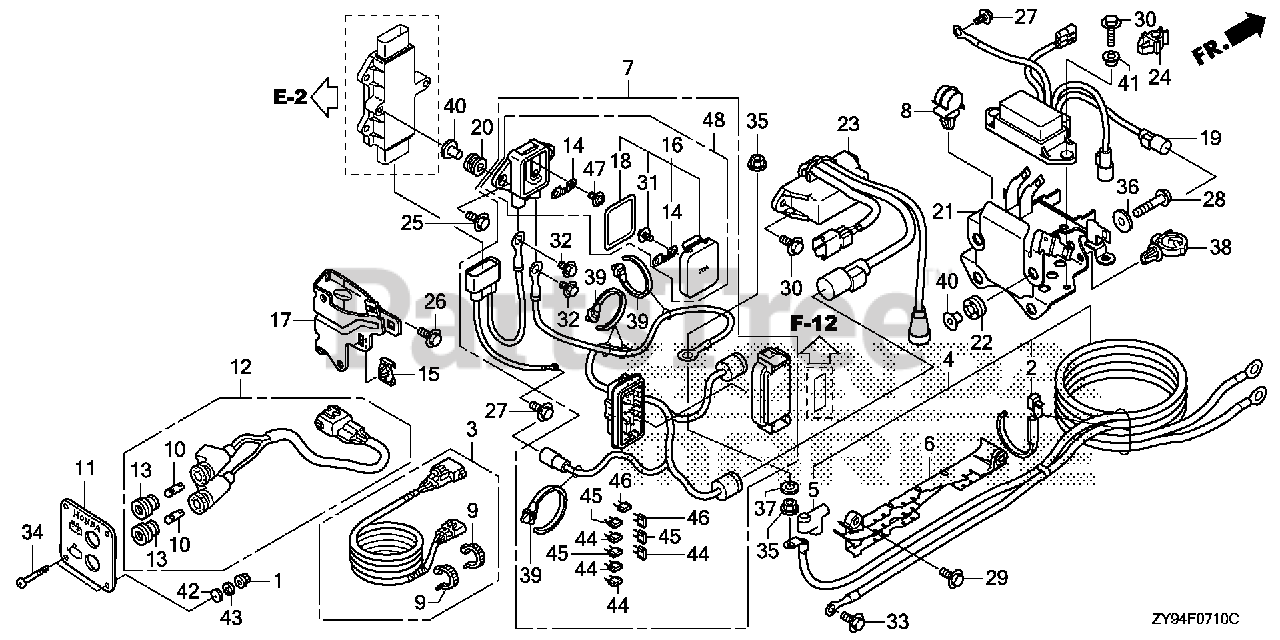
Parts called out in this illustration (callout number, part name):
1	NUT, FLANGE (5MM)
2	BAND, WIRE
3	WIRE ASSY., INDICATOR (3P/6P) (ANALOG)
4	CABLE ASSY., STARTER
5	COVER, STARTER TERMINAL
6	HOLDER, STARTER CABLE
7	CABLE ASSY., ALTERNATOR FUSE
8	CLAMP, WIRE
9	TIE, CABLE (2.4X92) (NATURAL)
10	BULB, WEDGE BASE (T6.5) (12V 3W)
11	PANEL, INDICATOR (2-BULB)
12	LAMP ASSY., INDICATION (2-BULB)
13	LENS, SPEEDOMETER PILOT
14	FUSE (70A)
15	CLIP, CONNECTOR HOLDER (B)
16	COVER ASSY., FUSE (70A)
17	BRACKET, FUSE BOX
18	GASKET, FUSE BOX COVER
19	RELAY ASSY., POWER TILT
20	GROMMET, RELAY
21	BRACKET, RELAY
22	GROMMET, RELAY BRACKET
23	RELAY ASSY., MAIN
24	CLIP C, BRAKE PIPE
25	BOLT-WASHER (6X27) (CT200)
26	BOLT, FLANGE (6X14) (CT200)
27	BOLT, FLANGE (6X12)
28	BOLT, FLANGE (6X28) (CT200)
29	BOLT, FLANGE (6X20)
30	BOLT, FLANGE (6X14)
31	SCREW-WASHER (3X7)
32	BOLT-WASHER (5X9)
33	BOLT, FLANGE (8X18)
34	SCREW, PAN (5X40)
35	NUT-WASHER (8MM)
36	WASHER, PLAIN (22X6X1.6)
37	WASHER, PLAIN (8MM)
38	CLIP, WIRE HARNESS (25MM)
39	CLIP, HARNESS BAND (145MM) (BLACK)
40	COLLAR, MODULE IGNITION CONTROL CASE (CDI)
41	COLLAR, P.T.T. RELAY
42	WASHER, PLAIN (5MM)
43	WASHER, SPRING (5MM)
44	FUSE, MINI (10A)
45	FUSE, MINI (15A)
46	FUSE, MINI (30A)
47	SCREW-WASHER (5X10)
48	BOX ASSY., FUSE (70A)
